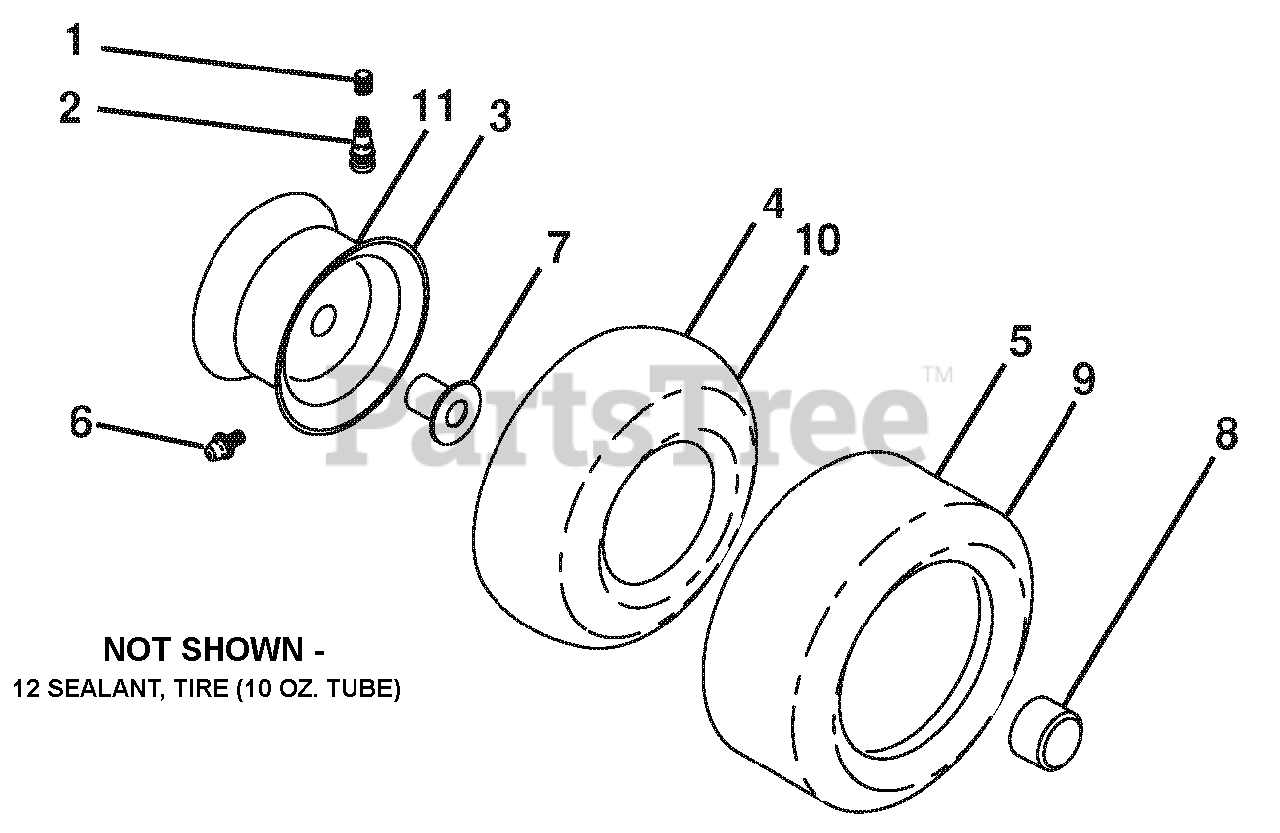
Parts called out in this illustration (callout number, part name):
1	CAP.VALVE.TIRE
2	STEM.VALVE
3	Rim.Asm.6"Front(w.Grey).643
4	TUBE.INNER.FRONT.#35060
5	TIRE.F.TS.15 X 6.0 - 6.SERVICE
6	FITTING.GREASE
7	BEARING.FLANGE
8	CAP.HUB.AXLE.BLK.1.50 X 1.00
9	TIRE.R.TS-LT.18X9.5-8.C.SERV.
10	TUBE.REAR.9.5 X 8.SERVICE
11	Rim Asm.8"Rear.W.Gry.Srvce.643
